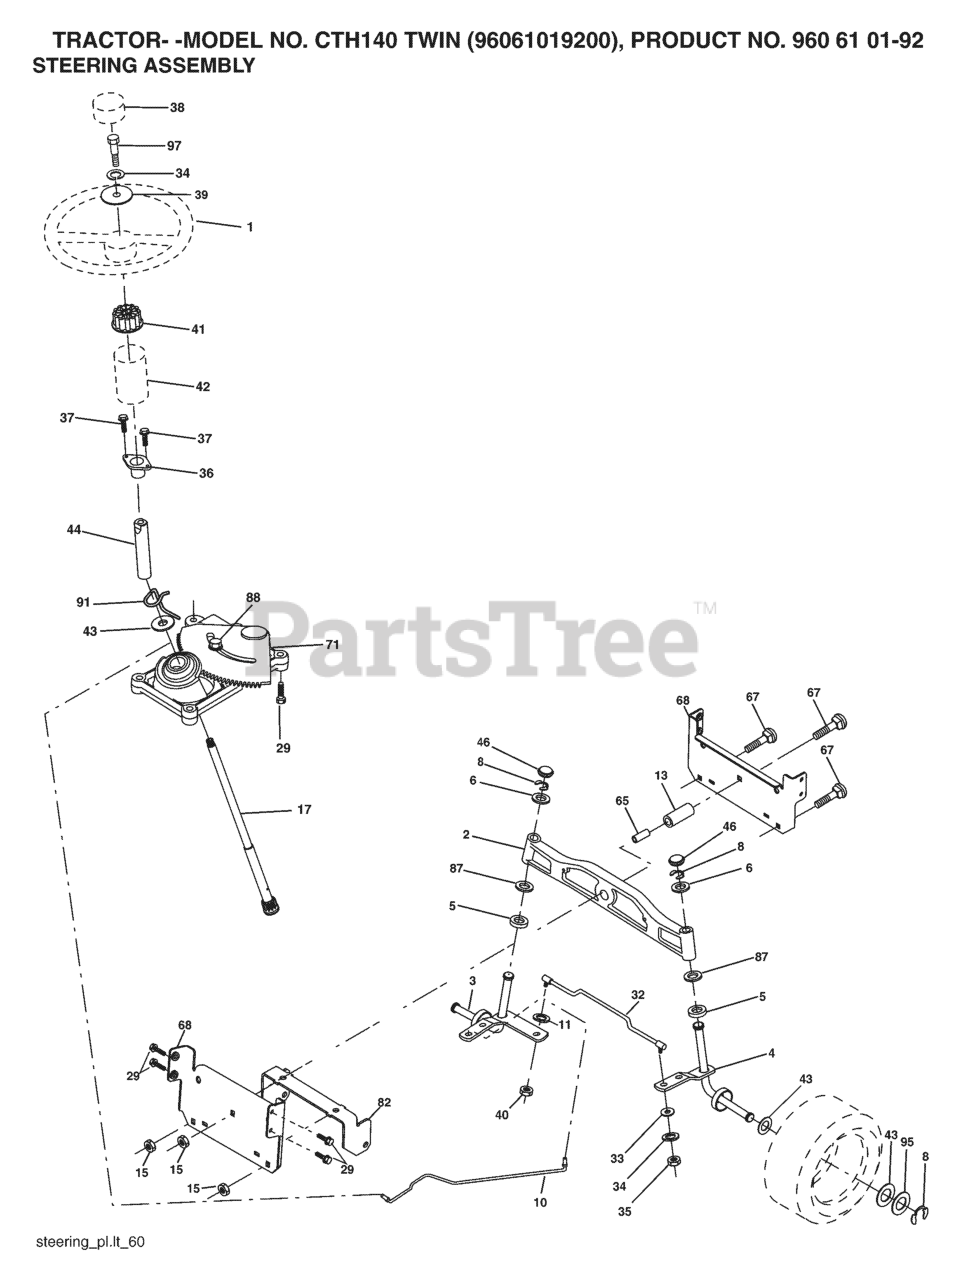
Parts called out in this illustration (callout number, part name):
1	STEERING WHEEL
2	AXLE ASSY FRONT
3	SPINDLE.ASM.LH.15"TIRES
4	SPINDLE.ASM.RH.15"TIRES
5	THRUST WASHER
10	DRAGLINK.15".TIRES.2001
11	WASHER, LOCK 3/8
13	TUBE, PIVOT AXLE
15	NUT
17	SHAFT STEERING SPLINE
29	SCREW, 3/8-16X3/4
33	WASHER M
34	WASHER.LOCK.HVY.HLCL.SPR.5/16
35	NUT, CROWNLOCK
36	BUSHING, STEERING
37	SCREW.TT.#10-32X.5.3/8.FLANGE
38	INSERT.CAP.STRG.WH.GRAY
39	WASHER.11/32
40	NUT CROWNLOCK 3/8-24
41	ADAPTER, WHEEL STNG..
42	BOOT, STEERING
44	SHAFT.EXTEN.STRG.SPLINE
46	CAP.SPINDLE.BLACK
65	SPACER BRACE AXLE
67	BOLT CARRIAGE
68	BRACE.AXLE.15"TIRES
71	STEERING ASM
82	BRACKET.SUSP.CHASSIS.FRONT.15
87	WASHER, FLAT .781 X 1 1/2"
88	BOLT, SHOULDER 7/16-20
91	CLIP.STEERING
95	WASHER.HARDENED
